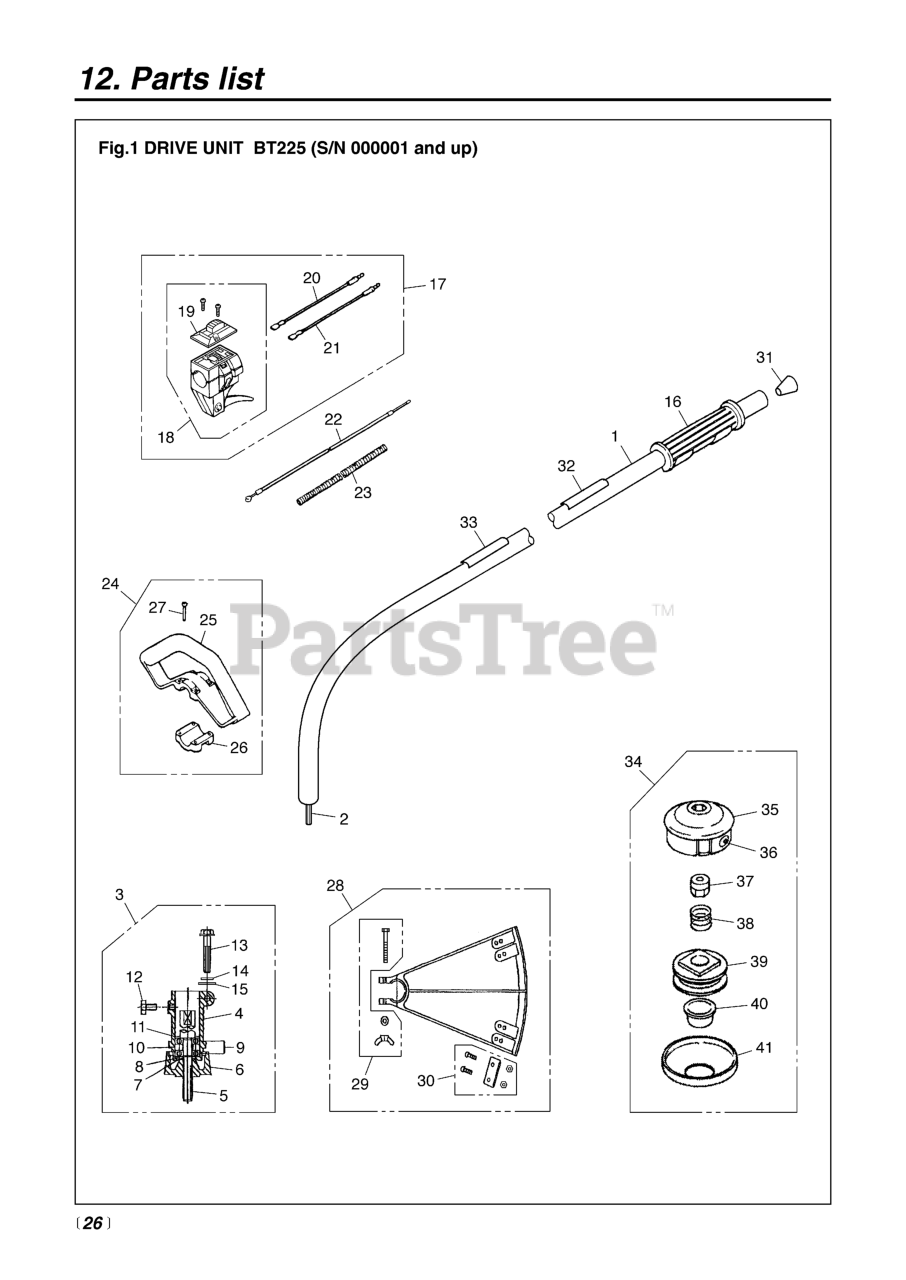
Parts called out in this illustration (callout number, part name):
1	PIPE COMP.
2	FLEX SHAFT
3	HOUSING ASSEMBLY
4	CASE
5	SHAFT
6	HOLDER
7	WASHER, M8
8	WASHER, M8
9	BEARING (RPLS. T4001-31340)
11	WASHER, M12
12	BOLT, M5 X 10
13	BOLT, M5 X 30
14	WASHER, M5
15	WASHER, M5 X .8
16	GRIP (RPLS 3577-32140 & 3220-
18	LEVER (USE 848-8R2-0313)
19	COVER (USE 848-8RA-0340)
20	CORD (A), BLACK
21	CORD (B), RED
22	CABLE COMP (RPLS 1633-83100)
23	TUBE
24	HANDLE ASSEMBLY
25	HANDLE
27	SCREW, M5 x 35
28	GUARD ASSEMBLY
29	GUARD MOUNTING ASSEMBLY
30	BLADE ASSEMBLY
31	END CAP, TUBE
32	LABEL FOR BT225
33	PLATE, CAUTION
34	HEAD (BT2201) (ACC.)
35	HOUSING
36	EYELET
37	UBTR-F10-RHF
38	SPRING
40	BUTTON
